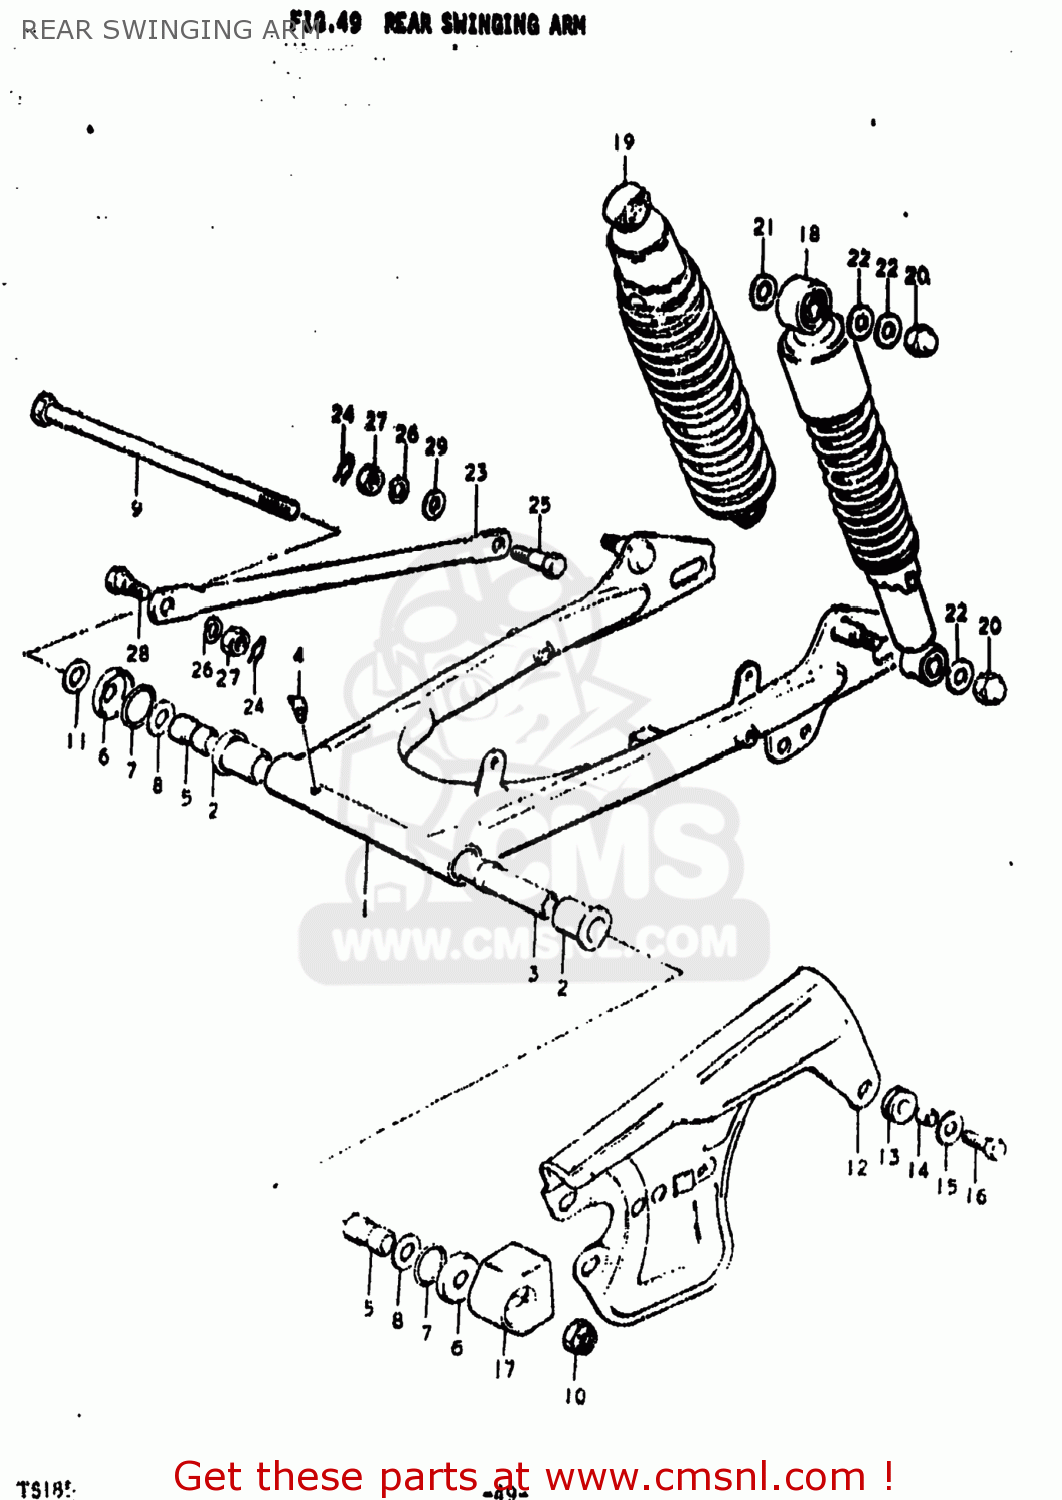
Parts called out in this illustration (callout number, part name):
1	SWING ARM ASSEMBLY,REAR
2	BUSHING
3	SPACER,SWING ARM,CENTER
4	NIPPLE,GREASE
5	SPACER,RR SWGARM PIVOT
6	COVER,SWGARM BUSH DUST SEAL
7	O RING(D:2,ID:24.5)
8	WASHER(12.5X24X2.3)
9	SHAFT,PIVOT
10	NUT
11	WASHER
12	CASE,CHAIN
13	CUSHION
14	SPACER (7X9X7)
15	WASHER (6.5X20X1.2)
16	BOLT
17	BUFFER,CHAIN TOUCH DEFENSE
18	ABSORBER ASSEMBLY,REAR SHOCK
19	ABSORBER ASSEMBLY,REAR SHOCK
20	NUT
21	WASHER
22	WASHER
23	TORQUE LINK,REAR
24	CLIP
25	BOLT(8X26.5)
26	LOCK WASHER
27	NUT
28	BOLT
29	WASHER
